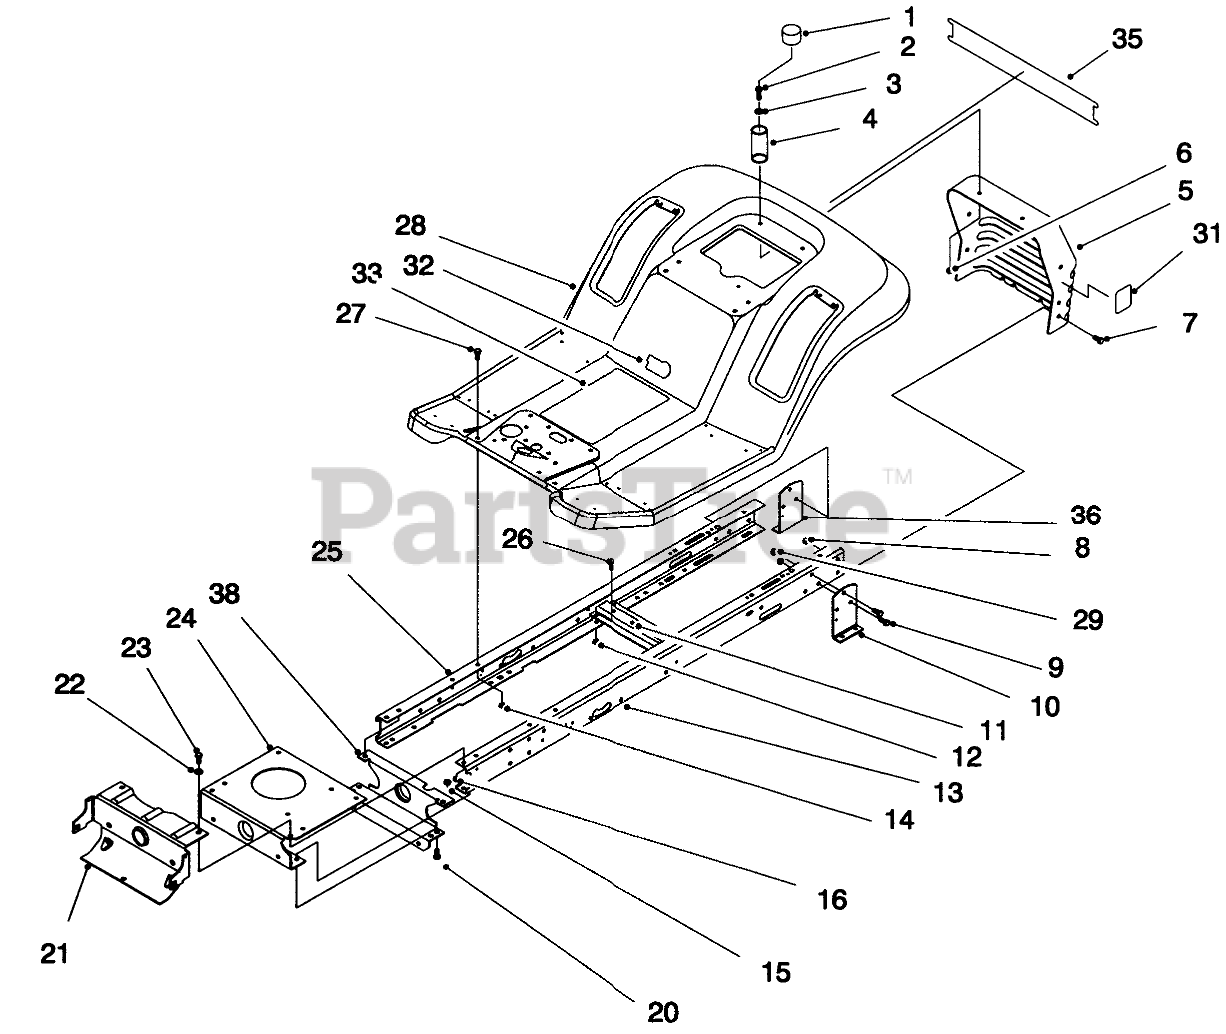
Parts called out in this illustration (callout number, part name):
1	CAP-PROTECTOR
2	SCREW-HH
3	WASHER-PLAIN
4	SPRING-COMPRESSION
5	Panel-Rear Hitch
6	NUT-LOCK, NI
7	SCREW-HH
8	NUT-LOCK, NI
9	SCREW-HH
10	Bracket-Trans. Mtg. L.H.
11	Bracket-Idle Pivot
12	NUT-LOCK, NI
13	Frame-Rail L.H.
14	NUT-LOCK, NI
15	NUT-LOCK, NI
16	NUT-LOCK, NI
20	SCREW-HH
21	Support-Front Axle
22	WASHER-PLAIN
23	SCREW-HH
24	Plate-Engine Mount
25	Frame-Rail R.H.
26	SCREW-HH
27	SCREW-HH
28	Body-Rear
29	NUT-LOCK, NI
31	DECAL - DUMP VALVE
32	Decal-Made In USA
33	Decal-Instruction Hydro
33	DECAL-INSTRUCTION
35	DECAL - REAR BODY
36	Bracket-Trans. Mtg. R.H.
38	Support-Rear
